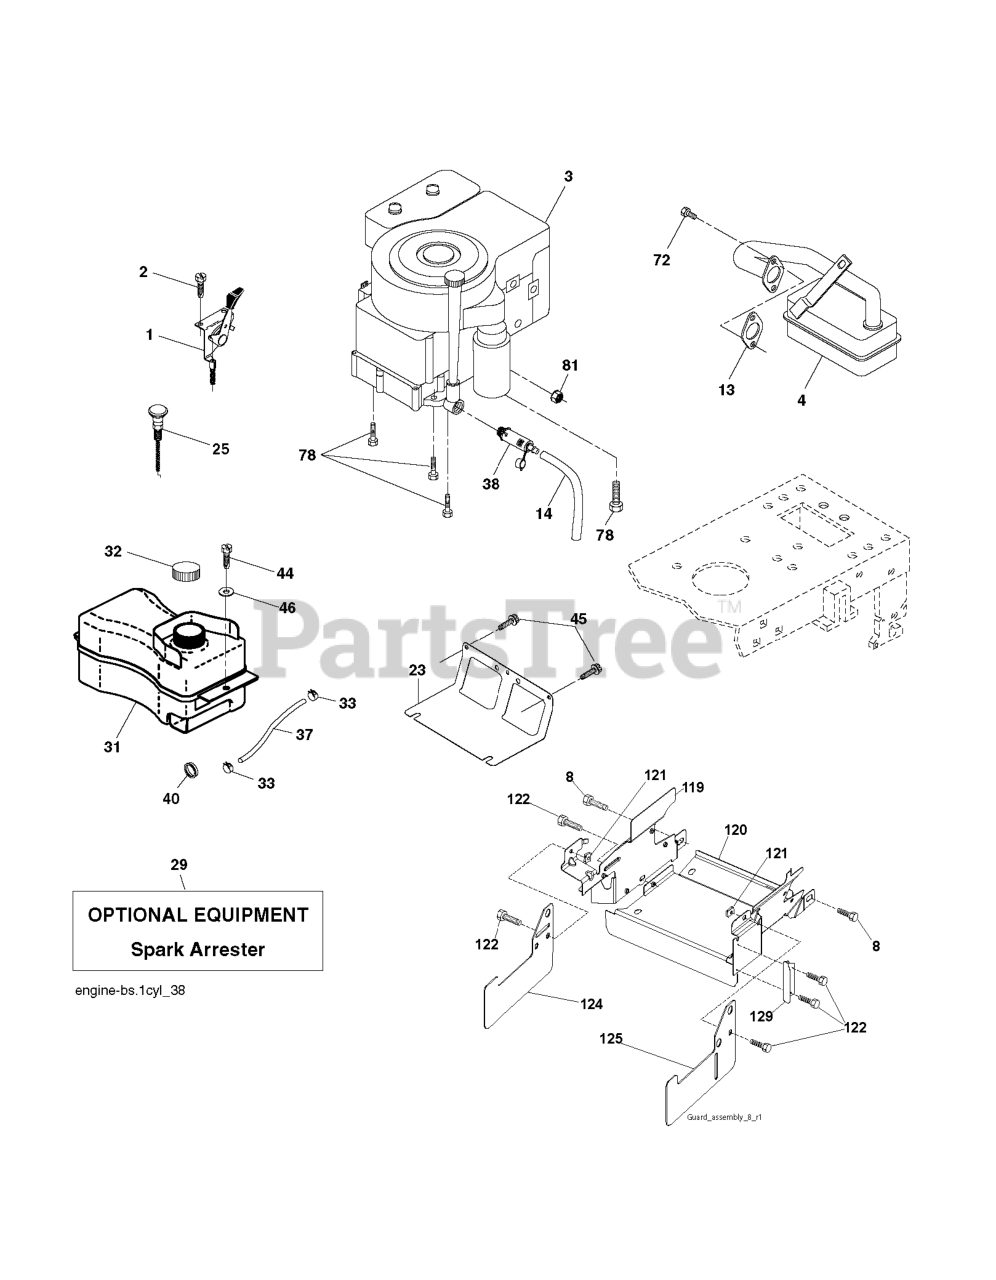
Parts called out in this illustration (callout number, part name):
1	CONTROL.THROTTLE/CHOKE.BLACK
2	SCREW
4	MUFFLER.B&S.MODEL.21.11HP.OHV
8	BOLT.5/16-18UNCX3/4 W/SEMS.BLK
13	REPL BY 532 27 22-93
14	TUBE, DRAIN OIL ASM.
23	SHIELD.BROWNING.DBR.GUARD
25	KNOB.ERGO.EXTENDED.RED (1 2)
29	KIT.SPARK ARRESTOR 794945 B&S
32	FUEL CAP
33	HOSE CLAMP
37	LINE.FUEL.20
38	PLUG DRAIN OIL EASY
40	BUSHING.SNAP.NYL.BLK.
44	SCREW HEXWSHR 1/4-20X3/4
45	SCREW, 3/8-16X3/4
72	SCREW.SOCKET HD.5/16-1
78	SCREW.3/8-16
81	NUT
122	SCREW.1/4-20X5/8
